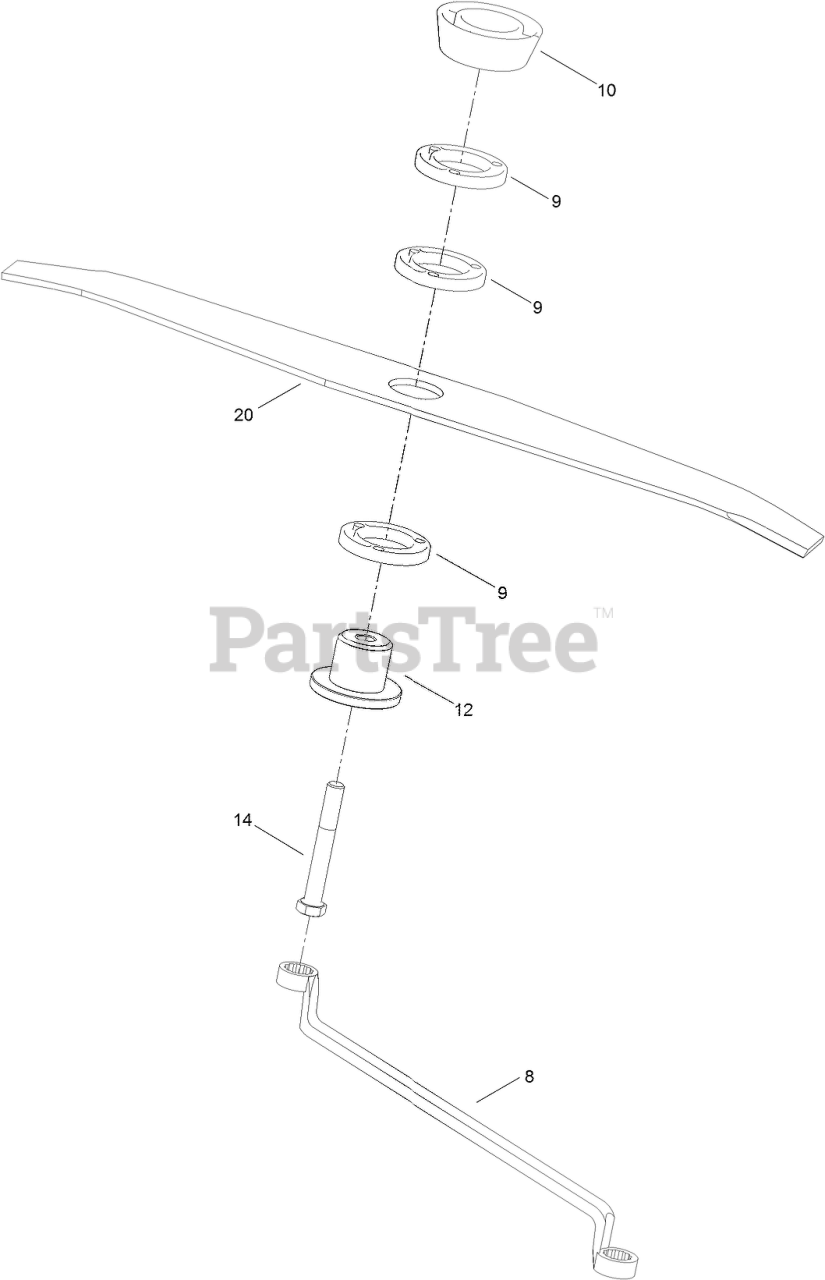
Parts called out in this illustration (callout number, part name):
8	SPANNER
9	SPACER-BLADE, ALUMINIUM
10	SPACER-DISTANCE
12	RETAINER-BLADE
14	SCREW-SET
20	BLADE (50 CM)
